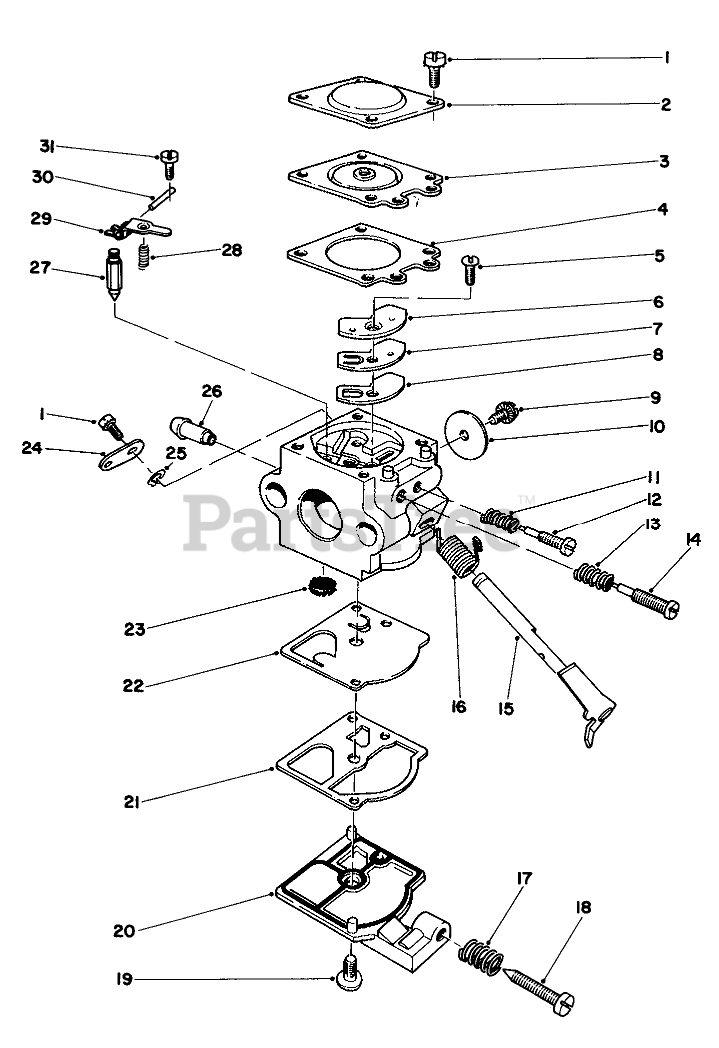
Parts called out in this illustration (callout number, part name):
1	Screw
1	MUFFLER SCREW
2	Cover, Diaphragm
2	WASHER-LOCK
3	METERING DIAPHRAGM
3	WASHER-FLAT
4	Gasket, Diaphragm
4	Screw-Heat Shield
5	Screw-Circuit Plate
5	Tab Shield
6	Plate, Circuit
6	EXHAUST GASKET
7	Diaphragm Circuit Plate
7	Muffler Assembly
8	Gasket-Circuit Plate
8	Arrester-Spark
9	Screw-Throttle Valve
9	MUFFLER OUTLET PLATE
10	Valve-Throttle
10	MUFFLER SHIELD
11	Spring, Needle
11	Screw-Outlet
12	Needle-Idle
13	Spring, HS Needle
14	Needle, HS
15	Shaft Assembly-Throttle
16	Spring-Throttle Lever
17	Spring-Idle Screw
18	Screw-Idle Adjust
19	Screw
20	Cover-Fuel Pump
21	PUMP GASKET
22	Diaphragm Fuel Pump
23	Inlet Screen
24	Lever-Throttle
25	Ring-Throttle Retainer
26	Fitting Fuel Inlet
27	INLET NEEDLE VALVE
28	METERING LEVER SPRING
29	Lever Metering
30	Metering Lever Pin
31	Screw-Metering Pin
